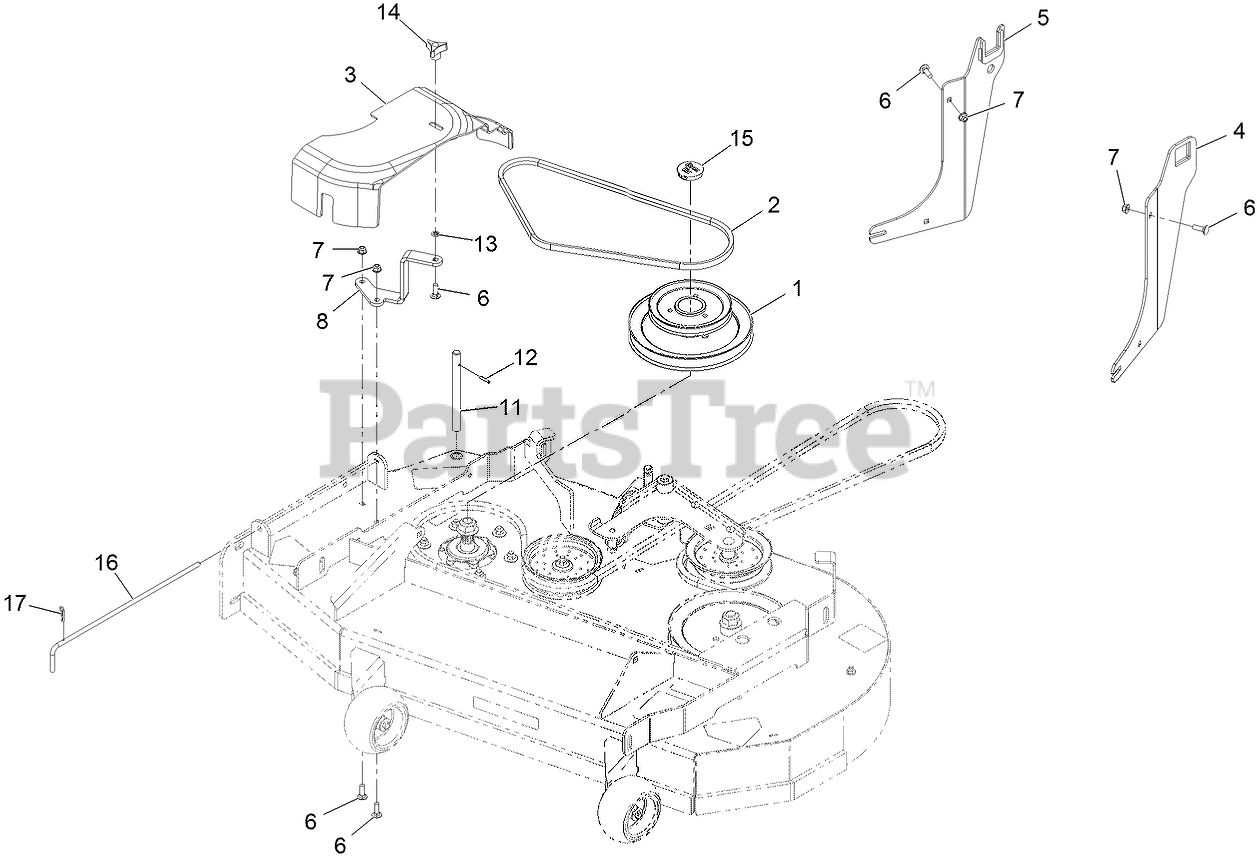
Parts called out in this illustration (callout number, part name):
1	JACKSHAFT,44 UV
2	BELT, BLOWER DRIVE 72
3	COVER-BELT, UV 44
4	BRACKET ASM, LH
5	BRACKET ASM, RH
6	BOLT-CARR
7	NUT-HF, NI
8	BRACKET-BELT COVER 44
11	SHAFT-CATCHER, GRASS
12	PIN-ROLL
13	RING-RETAINING, BOLT
14	KNOB-3 PRONG
15	PLUG, BLACK NYLON 1.75
16	PIN,CHUTE PIVOT
17	PIN-COTTER
